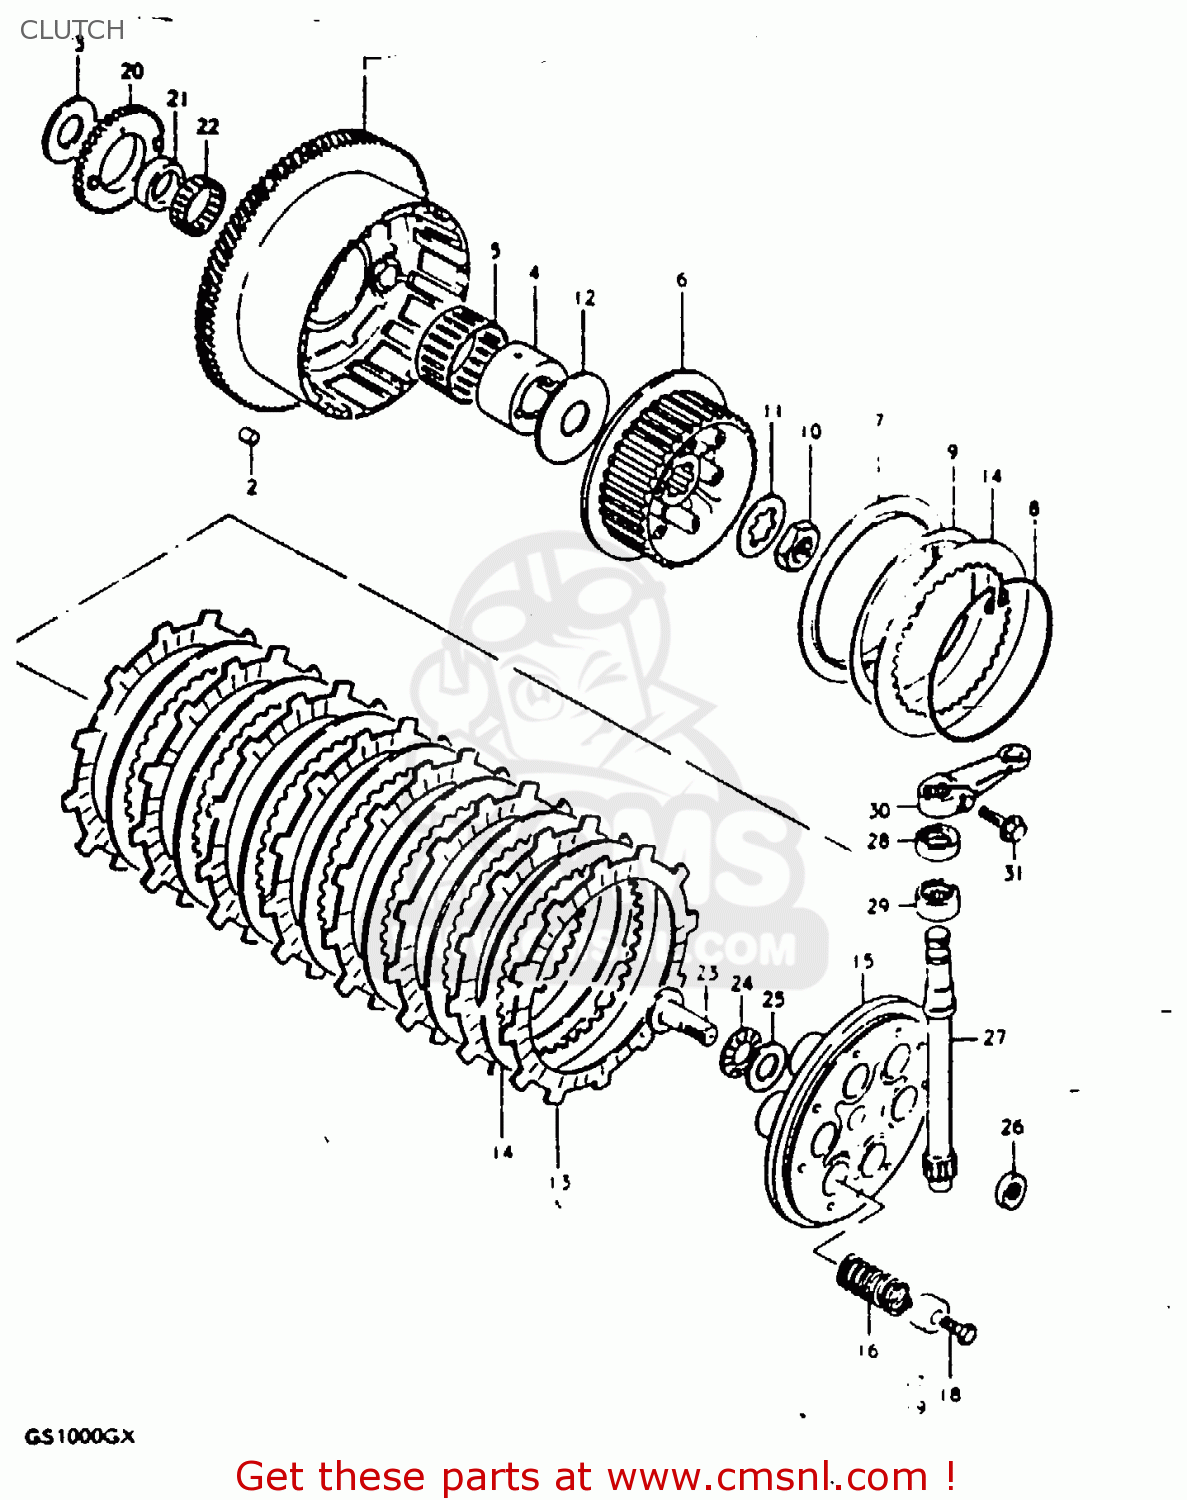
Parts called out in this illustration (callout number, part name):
1	GEAR ASSEMBLY,PRIMARY DRIVE
2	CUSHION,PRIMARY DRIVEN GEAR
3	WASHER
4	SPACER,PRIMARY DRIVEN
5	BEARING
6	HUB,CLUTCH SLEEVE
7	SEAT,WAVE WASHER
8	RING,STOPPER
9	WASHER
10	NUT
11	WASHER,LOCK
12	WASHER(25X66X3.5)
13	PLATE,CLUTCH DRIVE (MCA)
14	PLATE,CLUTCH DRIVEN (NAS)
15	PLATE,CLUTCH PRESSURE
16	SPRING
17	SPACER
18	BOLT
19	WASHER
20	GEAR,OIL PUMP DRIVE
21	SPACER,OIL PUMP DRIVE GEAR
22	BEARING(36X40X10)
23	RACK,CLUTCH RELEASE
24	BEARING(15X28X2)
25	WASHER
26	OIL SEAL
27	PINION,CLUTCH RELEASE
28	OIL SEAL
29	BEARING(15X22X12)
30	ARM,CLUTCH RELEASE
31	BOLT,REAR
